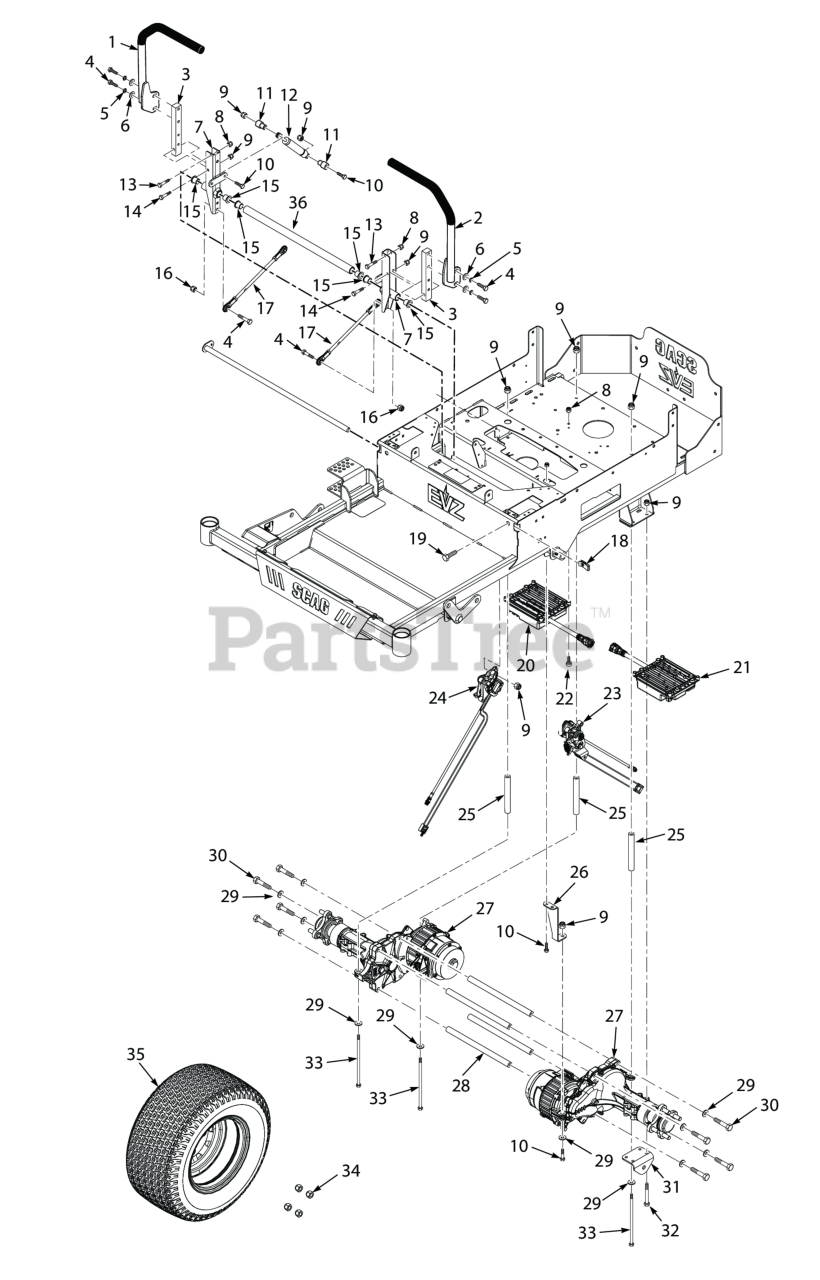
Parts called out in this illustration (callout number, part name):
1	Handlebar w/Grip
2	Handlebar w/Grip
3	Bar, Control Lever
4	Bolt, Hex Head 3/8-16 x 1-1/4", Kawasaki FX / FT & FT-EFI
5	Lockwasher, 3/8" Spring, Kawasaki FX / FT & FT-EFI / B&S 32BV
6	Flatwasher, 3/8" Special (.391 x .938 x .105)
7	Control Arm Assembly
8	HEX, NUT, ELASTIC STOP LOCK, 1/4-20
9	HEX NUT, ELASTIC STOP LOCK, 5/16-18
10	Bolt, Hex Head 5/16-18 x 1-1/2" (Right Front Engine Mounting, Briggs and Kohler Only)
11	Spacer, Pump Dampener
12	Damper, Steering
13	Bolt, Hex Head, 1/4-20 x 1-1/4"
14	Bolt, Hex Head 5/16-18 x 1-1/2" - Front
15	Bearing
16	HEX NUT, ELASTIC STOP LOCK, 3/8-16
17	Linkage, Pump
18	U-Nut, 3/8-16
19	Bolt, Hex Head 3/8-16 x 3.0
20	Drive Controller, RH
21	Drive Controller, LH
22	Cap Screw, Socket Head 1/4-20 x 1"
23	RTN Assembly, LH
24	RTN Assembly, RH
25	Spacer, Axle
26	Support, Axle
27	Transaxle, ZT2800e
28	Spacer, Axles
29	Flatwasher, 3/8 (.391 x .938 x .105 HD) Grade 8
30	Bolt, Hex Head 3/8-16 x 2-1/4" - 61"
31	Bracket, Pusharm
32	Bolt, Hex Head 5/16-18 x 3.00"
33	Bolt, Hex Head 1/2-13 x 7-1/2" (48"/52")
34	Wheel Nut, 1/2-20 x 13/16
35	WHEEL ASSY, 20 X 10-10
36	Tube, Brake
